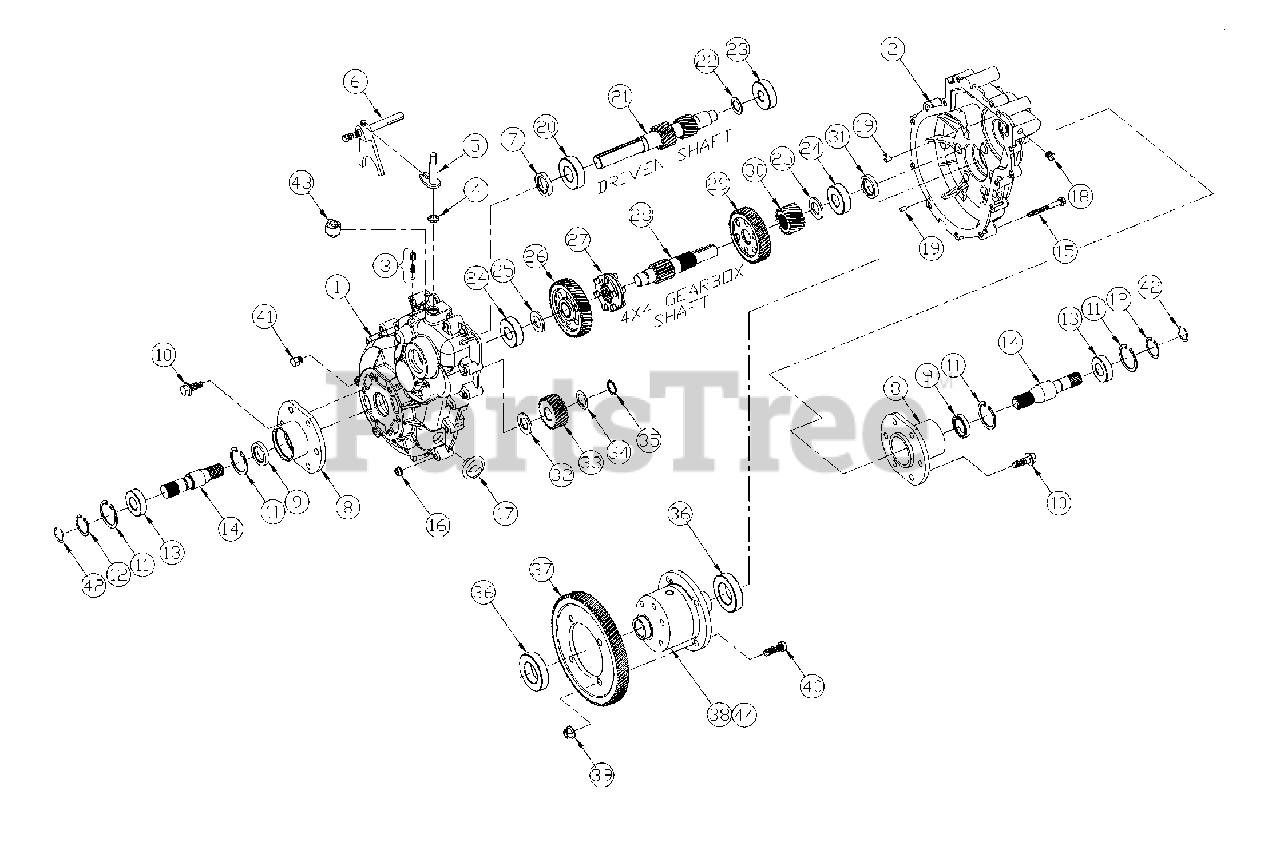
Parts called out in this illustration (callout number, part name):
1	DANA HOUSING AND SHAFT ASSBLY
2	DANA HOUSING-AXLE FIN
3	DANA KIT, DETENT
4	DANA SEAL - OIL
5	DANA ACTUATOR ASSY
6	DANA SHIFT ROD SUB-ASSY
7	DANA SEAL - OIL
8	REAR TUBE ASSY
9	SEAL - OIL
10	DANA SCREW - FLG HEAD
11	DANA RING, RETAINING
12	RING - RETAINER
13	BEARING - BALL SINGLE
14	SHAFT - AXLE, FIN
15	DANA SCREW - FLG HEAD
16	DANA NUT - LOCK
17	DANA PLUG - RUBBER
18	DANA VENT PLUG
19	DANA PIN - DOWEL
20	DANA BEARING 6205
21	DANA SHAFT - INPUT FIN
22	DANA KIT, SHIM
23	DANA BEARING -6303 BALL SINGLE
24	DANA BEARING -6204 BALL SINGLE
25	DANA SPACER - FLAT
26	DANA GEAR ASSY - FORWARD
27	DANA GEAR - CLUTCH
28	DANA SHAFT - INTERMEDIATE FIN
29	DANA GEAR ASSY - REVERSE
30	DANA GEAR - HELICAL FIN
31	DANA SEAL - OIL
32	DANA WASHER - THRUST
33	DANA GEAR ASSY - IDLER
34	DANA WASHER - THRUST
35	DANA RING - SNAP
36	DANA BEARING 6007
37	DANA GEAR - HELICAL FIN
38	DIFFERENTIAL, AUTO-LOCK
39	RPBY 35704
40	DANA BOLT - HEX
41	DANA DRAIN PLUG
42	RETAINER - SHAFT, AXLE
43	SWITCH, NEUTRAL, DANA GBOX
44	AUTO-LOK KIT
